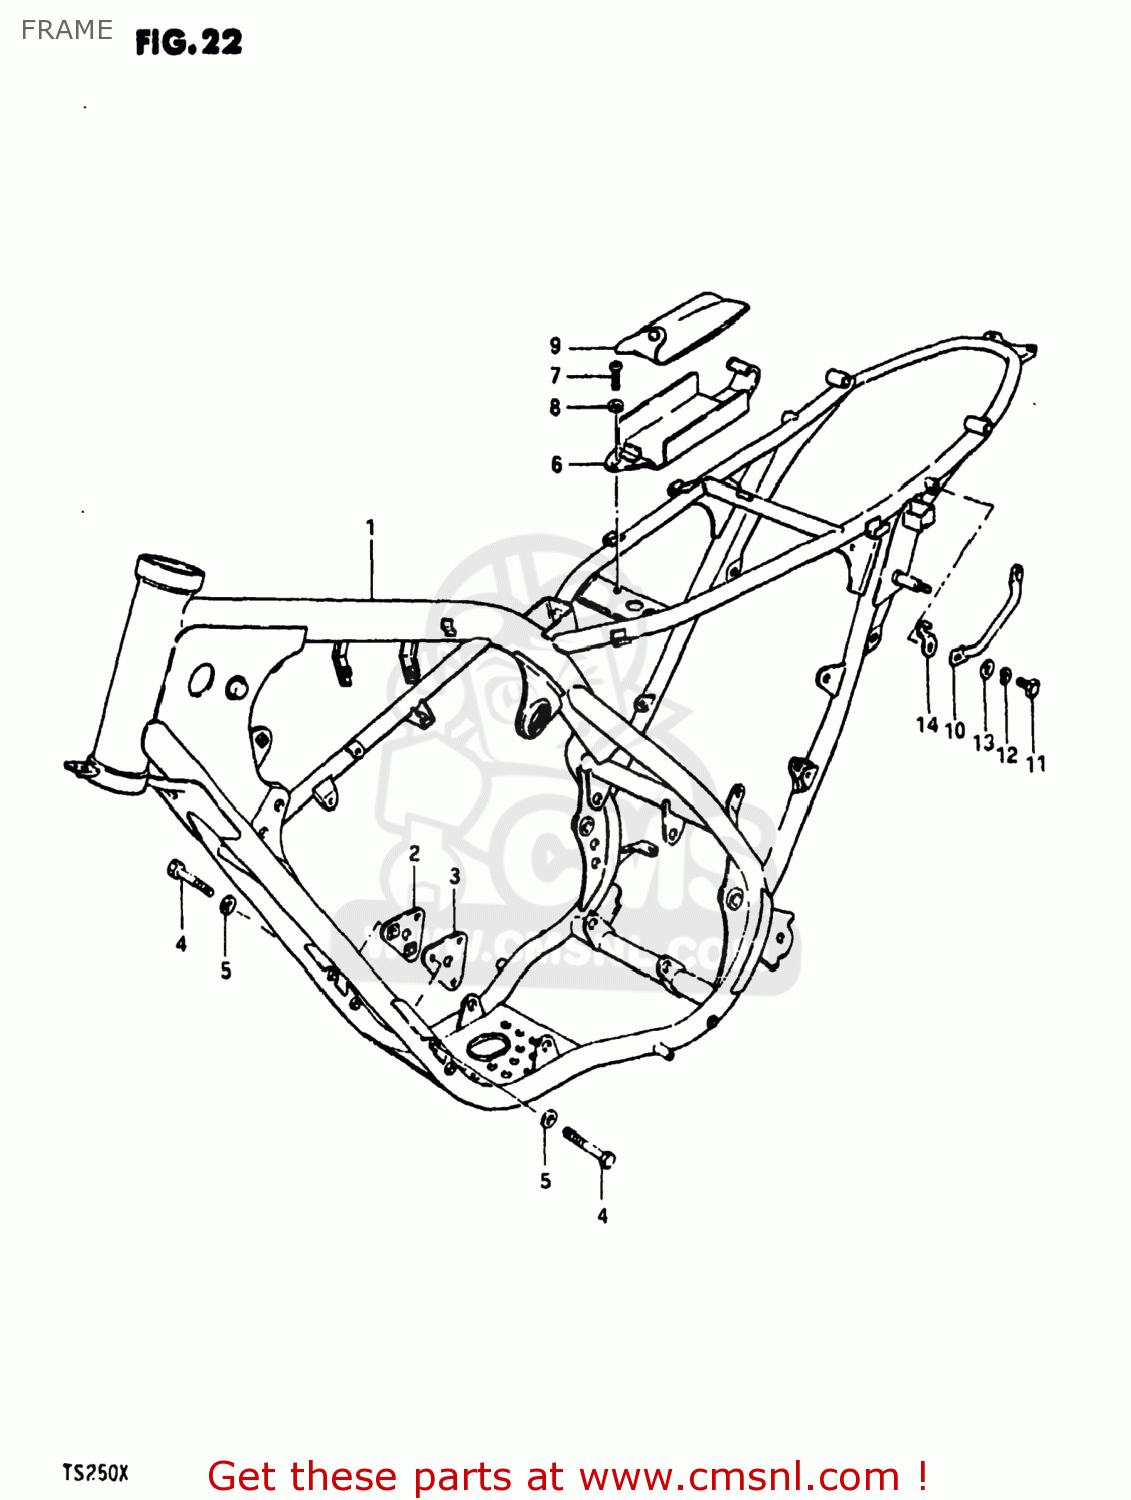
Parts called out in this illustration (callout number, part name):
1	FRAME
2	PLATE,ENGINE MOUNTING
3	PLATE,ENG MTG,L
4	BOLT 8X55
5	WASHER
6	HOLDER,TOOL
7	SCREW
8	WASHER
9	TOOL SET
10	GRIP,FRAME HANDLE
11	BOLT
12	LOCK WASHER
13	WASHER
14	HOOK,HELMET HOLDER
